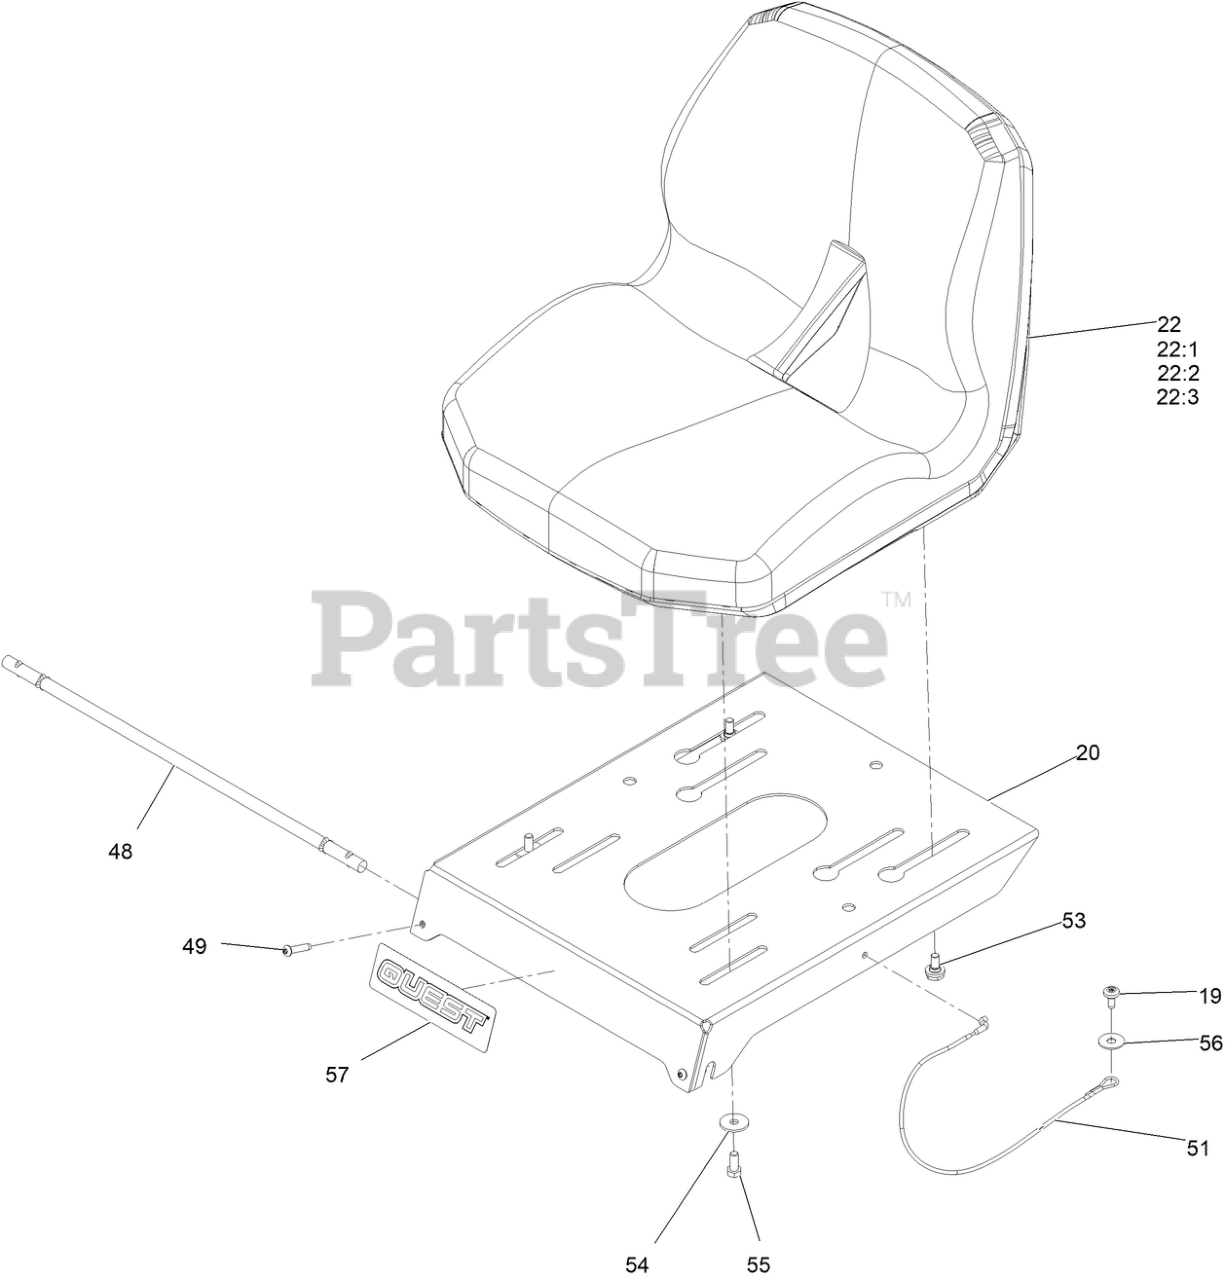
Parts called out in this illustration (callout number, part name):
19	SCREW-SHOULDER
22	Seat-16 In
22:1	SEAT-16 IN
22:2	Cover-Seat
22:3	SWITCH-BAIL
48	ROD-PIVOT
49	SCREW-BHCS
51	CABLE-LANYARD
53	BOLT-SHOULDER,HFH
54	WASHER-PIVOT
55	SCREW-HH
56	Washer-Flat
57	DECAL-QUEST LOGO
